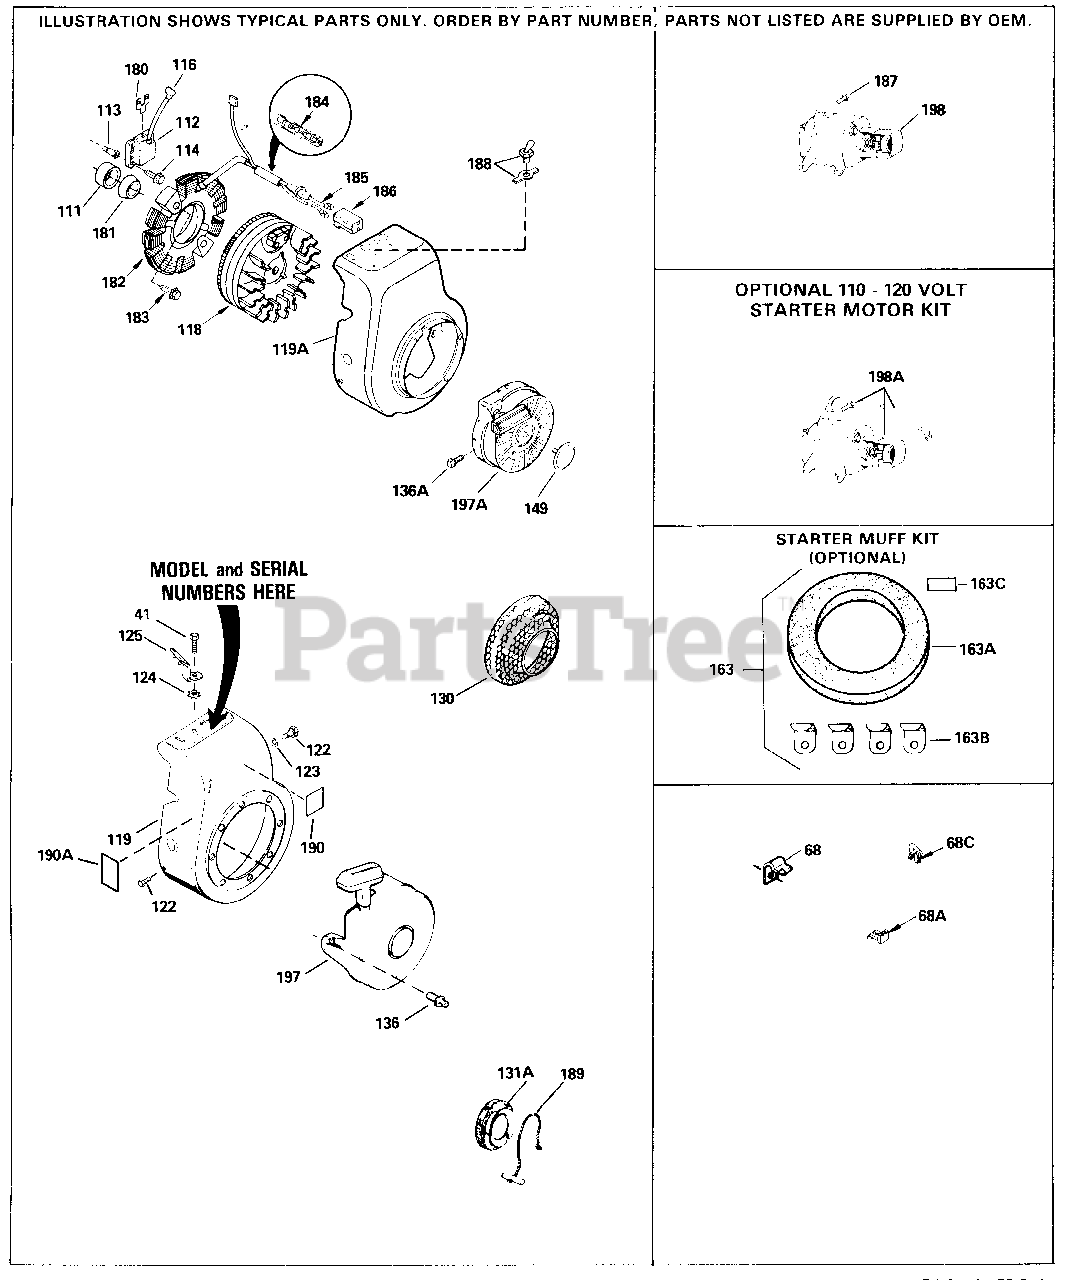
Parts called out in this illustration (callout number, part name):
41	Screw, 5/16-18 x 1-1/2" Use as requir ed
41	Screw, 5/16-18 x 2-1/4" Use as requir ed
41	Screw, 5/16-18 x 2" (Use as required)
111	Spacer, Flywheel key
112	Solid State Ass'y.
113	Stud, Solid State mounting
114	Screw, Torx T-15, 10-24 x 1"
116	Spark Plug Cover
116	Cover, Spark plug (Use as required)
118	Flywheel
119	Housing, Blower NOTE: In original pr oduction, the starter may be riveted to theblower housing. If the starter or blower housing needs replacement, the other may need holes used for po p rivetingenlarged to use standard mo unting hardware. Order 4
122	Screw, 1/4-28 x 7/16"
124	Lockwasher, 5/16
125	Clip, Spark plug shorting
130	Screen, Starter
163	Str.Muff Kit (Incl. 163A,163B,163C) O pt .
163A	Air Cleaner, Starter (Optional)
163B	Bracket, Starter air cleaner Optiona l
163C	Decal, Instruction (Optional)
190	Decal, Name
197	Starter, Rewind In original productio n, the starter may be riveted to the blowerhousing. If the starter or blow er housing needs replacement, the oth er may need holes used for pop riveti ng enlargedto use standard mounting h ardware. Order 4 nuts (
198A	Electric Starter Motor (120 volt) Thi s 120-Volt starter motor kit can be u sed on those models equipped with ele ctric starter provisions. Refer to D ivision 5, Section D, Page 16 for bre akdown.
